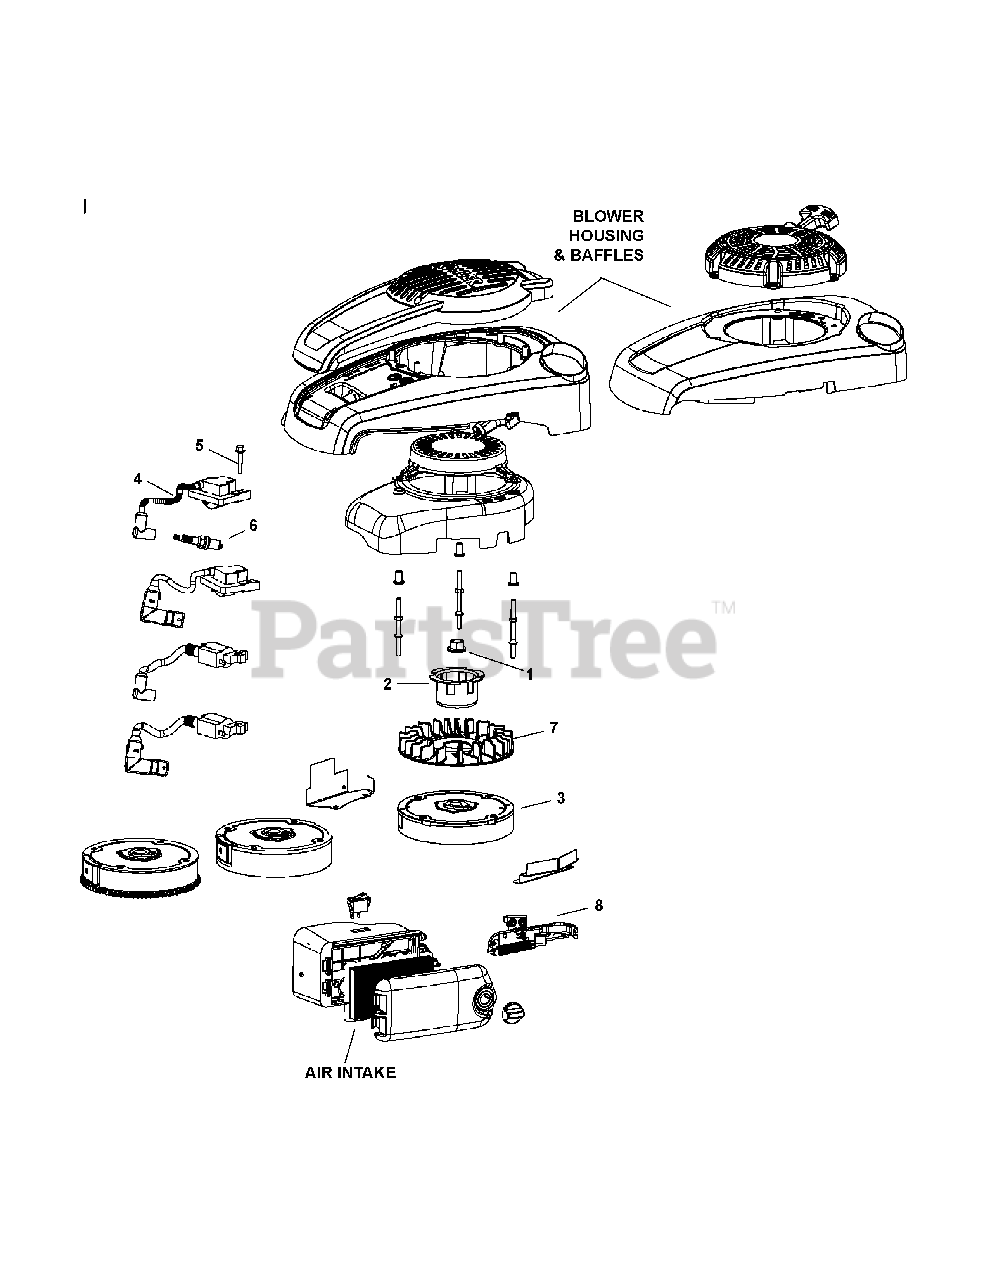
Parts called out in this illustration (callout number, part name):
1	Nut, Flywheel (w/ serrations)
3	Flywheel Assembly
4	Ignition Module
5	Hex Flange Screw, M6
6	Spark Plug
7	Flywheel Fan
8	Brake Assembly, ES
